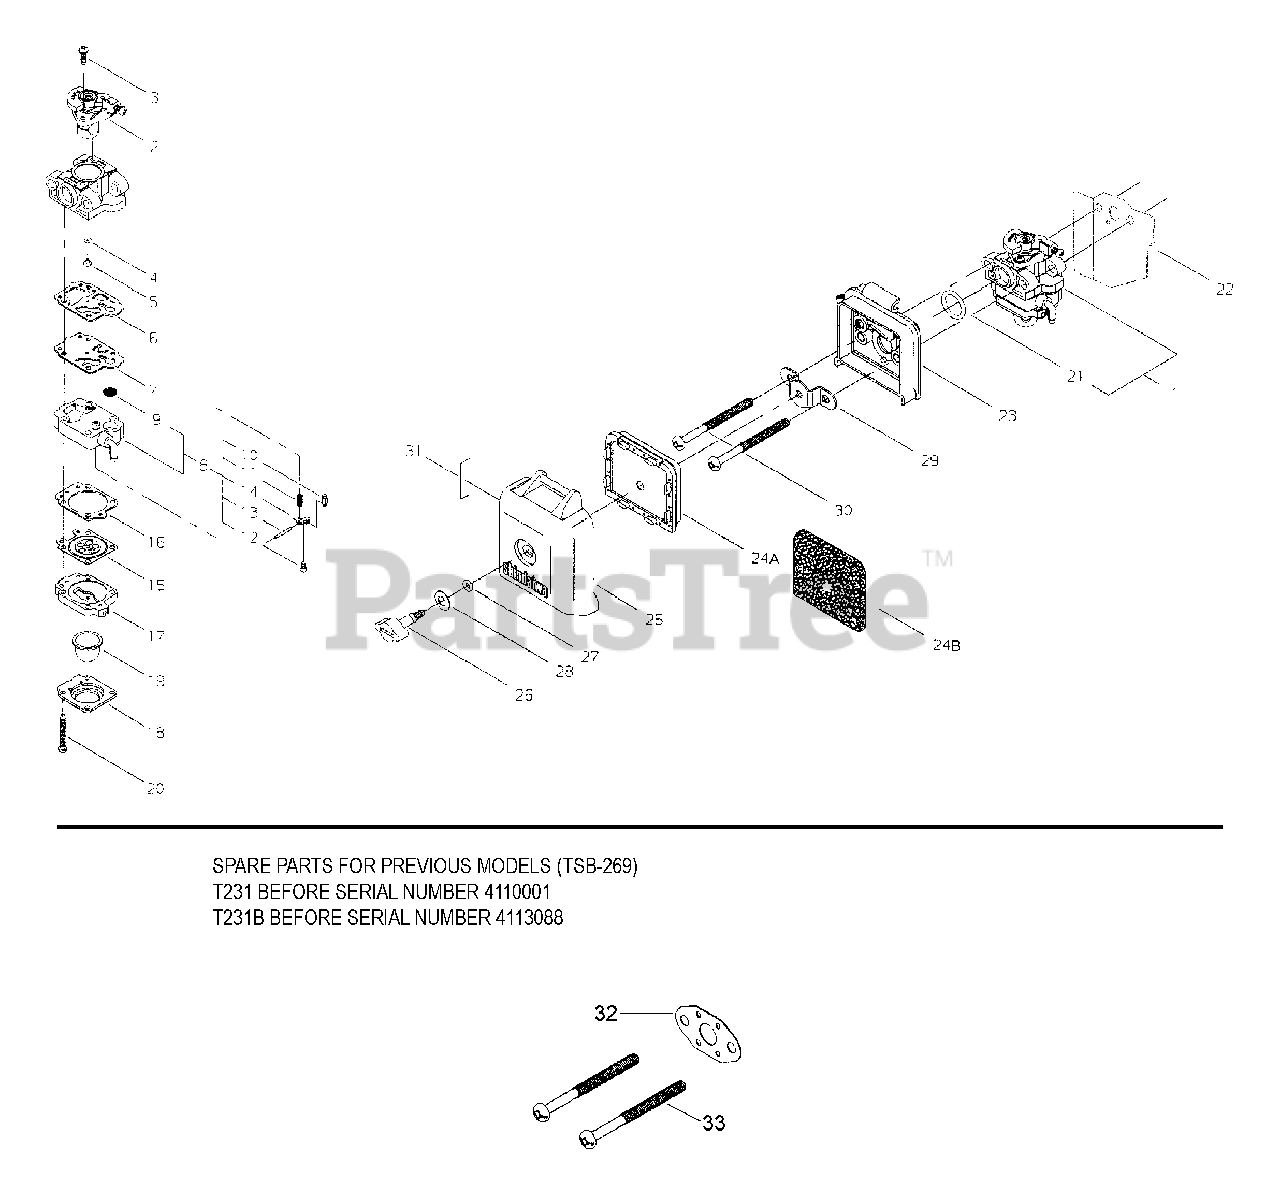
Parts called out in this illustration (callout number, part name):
1	CARBURETOR
2	VALVE ASSY, THROTTLE
3	SCREW, THROTTLE COLLAR
4	O-RING
5	JET, MAIN
6	GASKET, PUMP
7	DIAPHRAGM, PUMP
8	BODY ASSY, PUMP
9	SCREEN, FUEL INLET
10	VALVE, INLET NEEDLE
11	SPRING, METERING LEVER
12	SCREW
13	PIN, METERING LEVER
14	LEVER, METERING
15	DIAPHRAGM, METERING
16	GASKET, METERING DIAPHRAGM
17	BODY ASSY, PURGE
18	RETAINER, PURGE BULB
19	BULB, PURGE
20	SCREW
21	O-RING 15
22	GASKET, CARBURETOR
23	CASE, AIR FILTER
24A	FILTER, AIR
24B	FILTER, AIR
25	COVER, AIR FILTER
26	THUMBSCREW
27	O-RING
28	WASHER, CONE M6
29	BRACKET
30	SCREW M5×60
31	LABEL, CHOKE
32	GASKET, CARBURETOR
33	SCREW - 5×67
